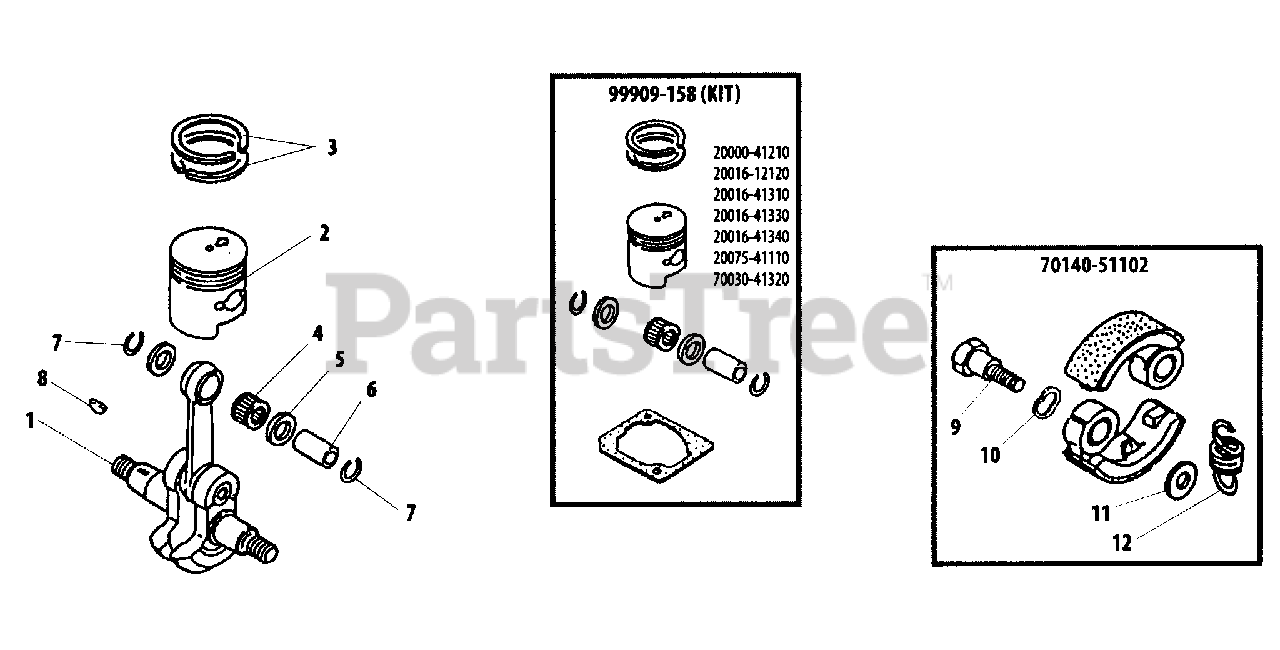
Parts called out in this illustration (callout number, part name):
1	CRANKSHAFT ASSY
2	PISTON
3	RING, PISTON
4	BEARING, NEEDLE
5	WASHER, THRUST
6	PIN, PISTON
7	RING, RETAINING
8	KEY - 3X10
9	BOLT, CLUTCH
10	WASHER - SPRING
11	WASHER - 6
12	SPRING, CLUTCH
70140-51102	CLUTCH ASSY
99909-158	PISTON ASSY
